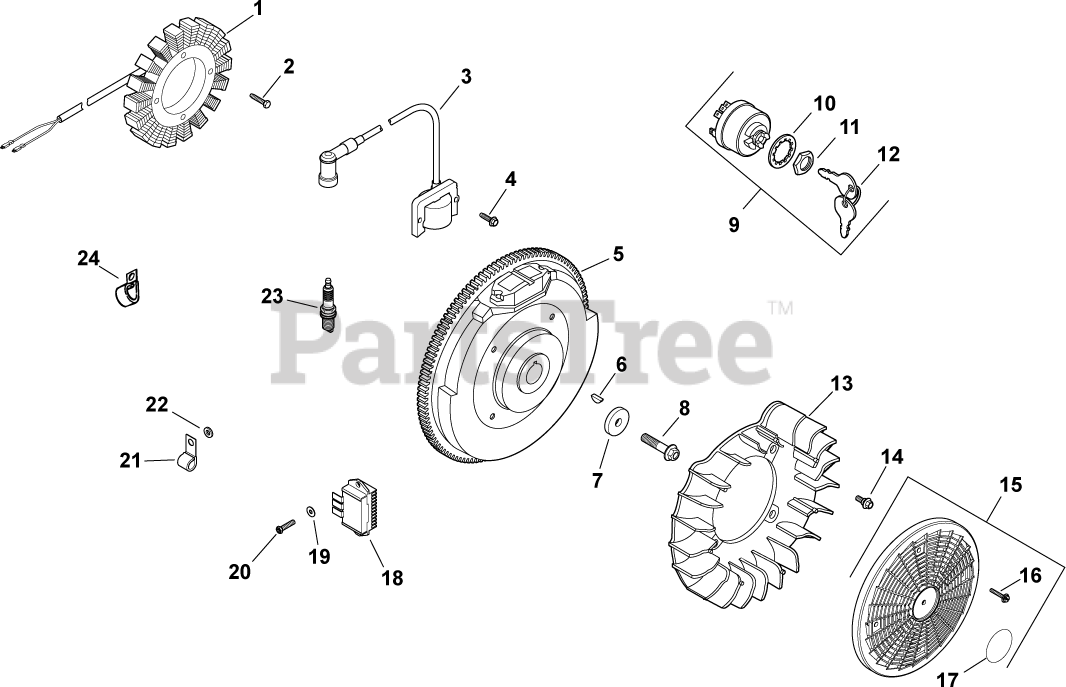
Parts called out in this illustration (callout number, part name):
1	KIT, 15 / 20 AMP STATOR
2	SCREW, M5X0.8X25 - (#25086402S)
3	KIT, MODULE IGNTN (CDI FIXED)
4	SCREW, FLG THD FRM M5X.8X20-(#25086399S)
5	FLYWHEEL, PAINTED-USE 24 025 59-S
6	KEY, 3/16" X 5/8"
7	WASHER, FLAT 13/32"
8	SCREW, FLG M10X1.5X45 - (#25086361S)
9	SWITCH ASSY, KEY (KM)-USE 25 099 32-S
10	WASHER, INTERNAL TOOTH
11	NUT, KEY SWITCH
12	KEY, SET -USE 48 340 01-S
13	FAN USE 24 755 253-S
14	BOLT, SHOULDER
15	KIT, GRASS SCREEN
16	SCREW, FLG SEMS M4X.7X25
17	DECAL, GRASS SCREEN USE 24 113 499-S
18	REG/RECTIFIER (20/25 AMP)-USE 25 403 20-
19	WASHER, FLAT 7/32"
20	SCREW, HEX FLANGE HI-LO
21	CLIP, CABLE
22	WASHER, FLAT 1/4" (O.D. 1/2")
23	PLUG, SPARK (STD)
24	CLIP, TUBE & WIRING (KM)
